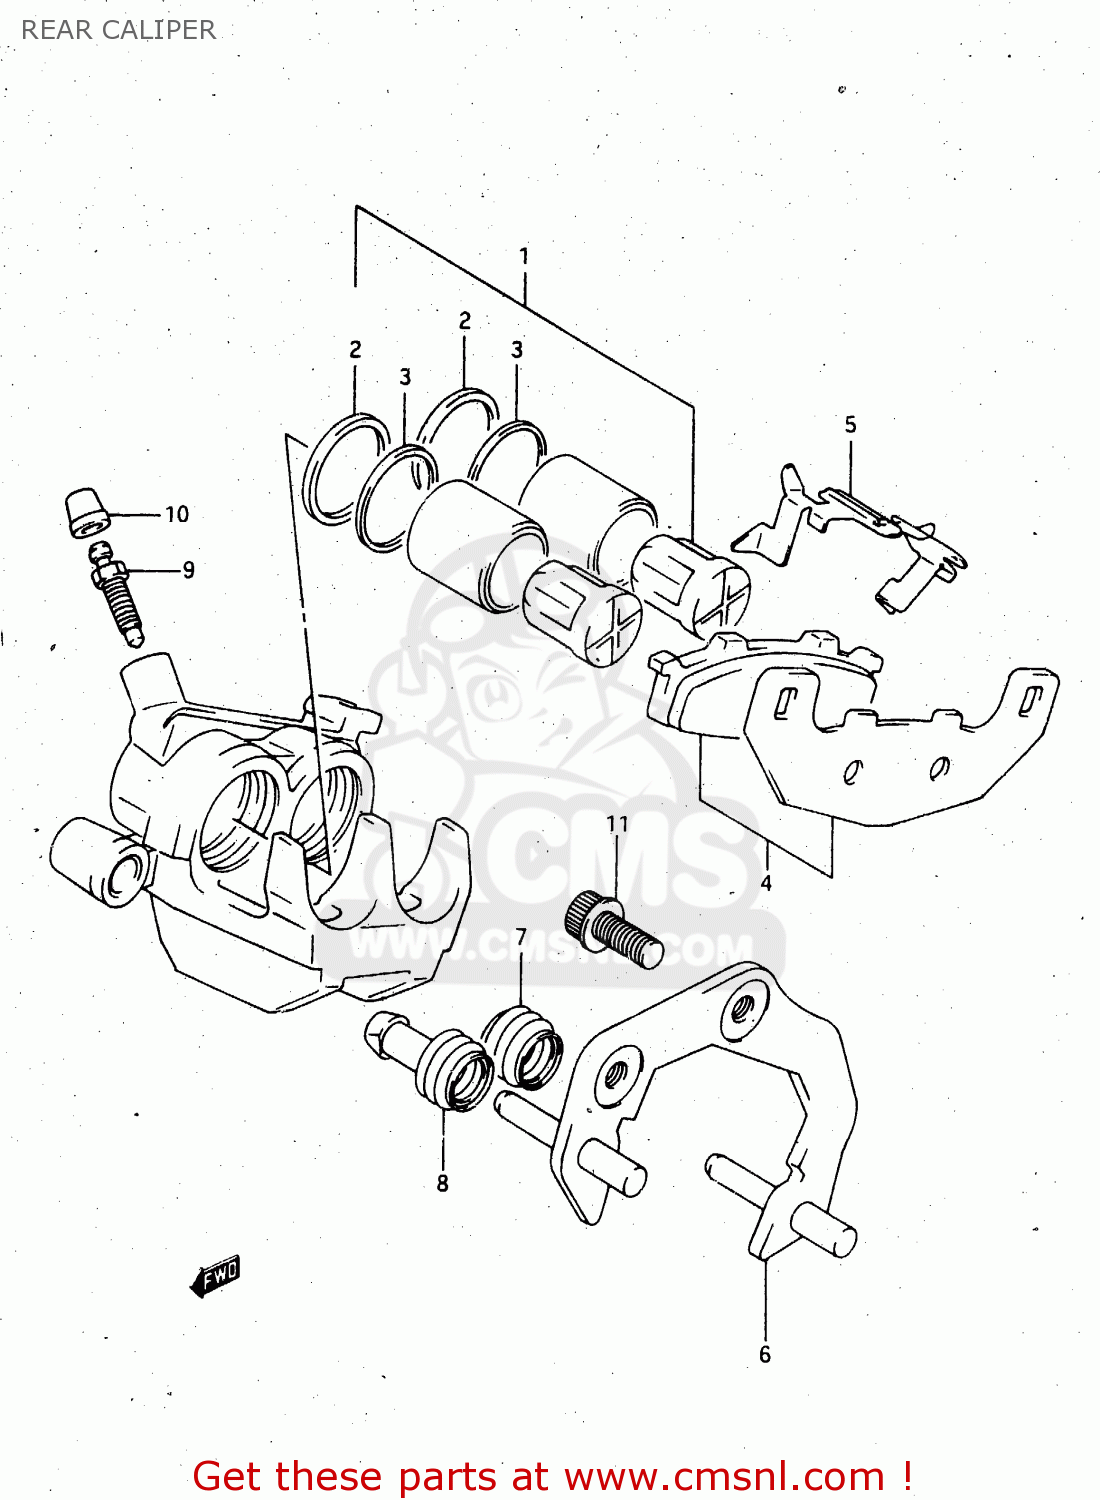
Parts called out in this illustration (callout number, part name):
1	PISTON SET
2	SEAL,PISTON
3	SEAL,WIPER
4	PAD SET (NAS)
5	SPRING, PAD
6	CARRIER,CALIPER
7	BOOT,AXLE
8	INSULATOR,AXLE
9	BLEEDER
10	CAP,BLEEDER PLUG
11	BOLT
